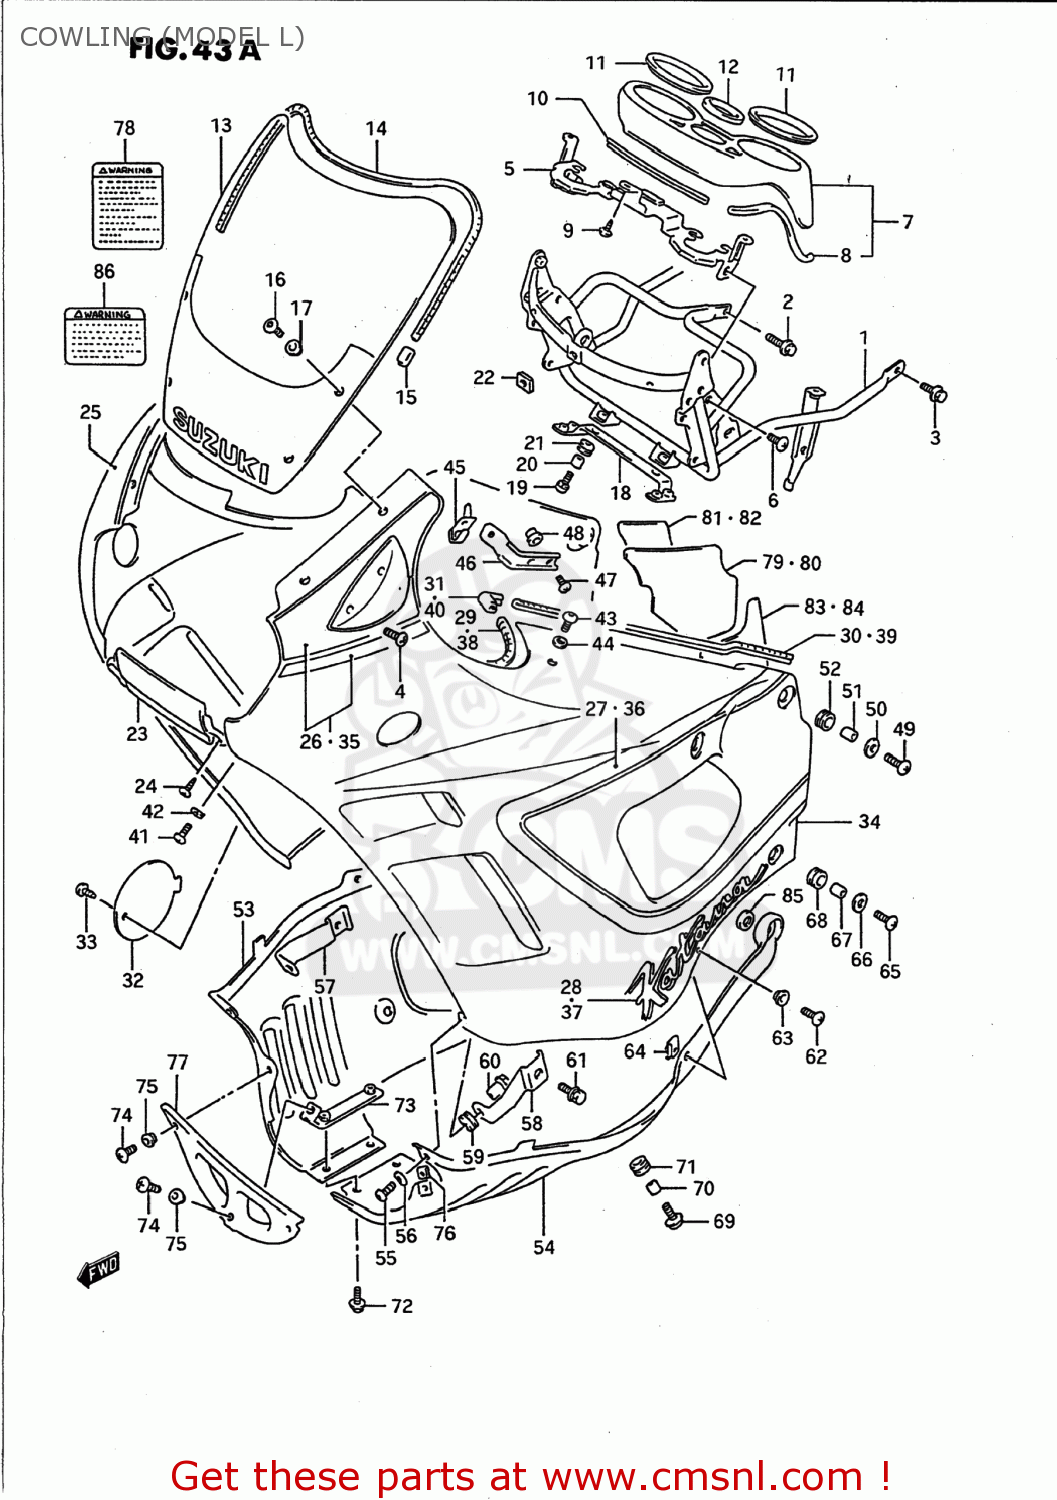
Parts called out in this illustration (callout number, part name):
1	BRACE,COWLING
2	BOLT
3	BOLT 6X12
4	SCREW 6X12
5	PLATE,METER FITING
6	SCREW 6X12
7	COVER COMP,METER
8	MOLDING
9	SCREW 5X8
10	MOLDING,METER COVER
11	CUSHION,SPEEDOMETER
12	CUSHION,FUEL METER
13	WINDOW,COWLING
14	MOLDING
15	CAP,MOLDING END
16	SCREW
17	WASHER(5.2X11X1)
18	PLATE,COWL CTR PANEL
19	SCREW(6X20)
20	SPACER (6,8X10X9.4)
21	CUSHION
22	CUSHION,SCREEN
23	PANEL,COWLING CTR
24	SCREW
25	COVER ASSEMBLY,COWLING,RIGHT
26	TAPE SET,COWL SIDE,R
27	TAPE,COWLING SIDE,RIGHT
28	EMBLEM,COWLING
28A	COVER,COWLING METER,SIDE
28B	COVER,COWLING METER SIDE,R
28C	SCREW
29	MOLDING
30	MOLDING
31	JOINT,MOLDING END
32	LID,OIL
33	SCREW(6X16)
34	COVER ASSEMBLY,COWLING,LEFT
35	TAPE SET,COWLING SIDE
36	TAPE,COWLING SIDE,LEFT
37	EMBLEM,COWLING
37A	COVER,COWLING METER,SIDE
37B	COVER,COWLING METER SIDE,L
37C	SCREW
38	MOLDING
39	MOLDING
40	JOINT,MOLDING END
41	SCREW(6X25)
42	WASHER(6.5X18X1.5)
43	SCREW(6X16)
44	WASHER(6.3X16X1.5)
45	BRACKET,COWLING UPR,R
46	BRACKET,COWLING UPR,L
47	SCREW(6X25)
48	NUT,COWLING SIDE BRKT
49	SCREW(6X25)
50	WASHER(6.5X18X1.5)
51	SPACER (6.1X9X9)
52	CUSHION
53	COVER,COWLING UNDER,R
54	COVER,COWLING UNDER,L
55	SCREW(6X30)
56	WASHER(6.5X18X1.5)
57	BRACKET,COWLING LWR,R
58	BRACKET,COWLING LWR,L
59	CUSHION
60	NUT,COWLING,FR
61	BOLT
62	SCREW(5X14)
63	WASHER(5.2X14X1.5)
64	NUT,HEADLAMP HOUSING,UPPER
65	SCREW(6X25)
66	WASHER(6.5X18X1.5)
67	SPACER(6.1X8X14.5)
68	CUSHION
69	SCREW(6X20)
70	SPACER (6.1X9X9)
71	CUSHION
72	SCREW, LOWER
73	BRACKET,FR UNDER COWL
74	SCREW
75	WASHER(5.2X14X1.5)
76	NUT,HEADLAMP HOUSING,UPPER
77	COVER,COWLING UNDER FR
78	LABEL (WARNING SCREEN)
79	BALANCER SHEET,COWLING,R
80	BALANCER SHEET,COWLING,L
81	CUSHION,COWLING,R
82	CUSHION,COWLING,L
83	SHEET,COWLING BALANCER,R
84	SHEET,COWLING BALANCER
85	CUSHION,UNDER COWLING RR
86	LABEL
